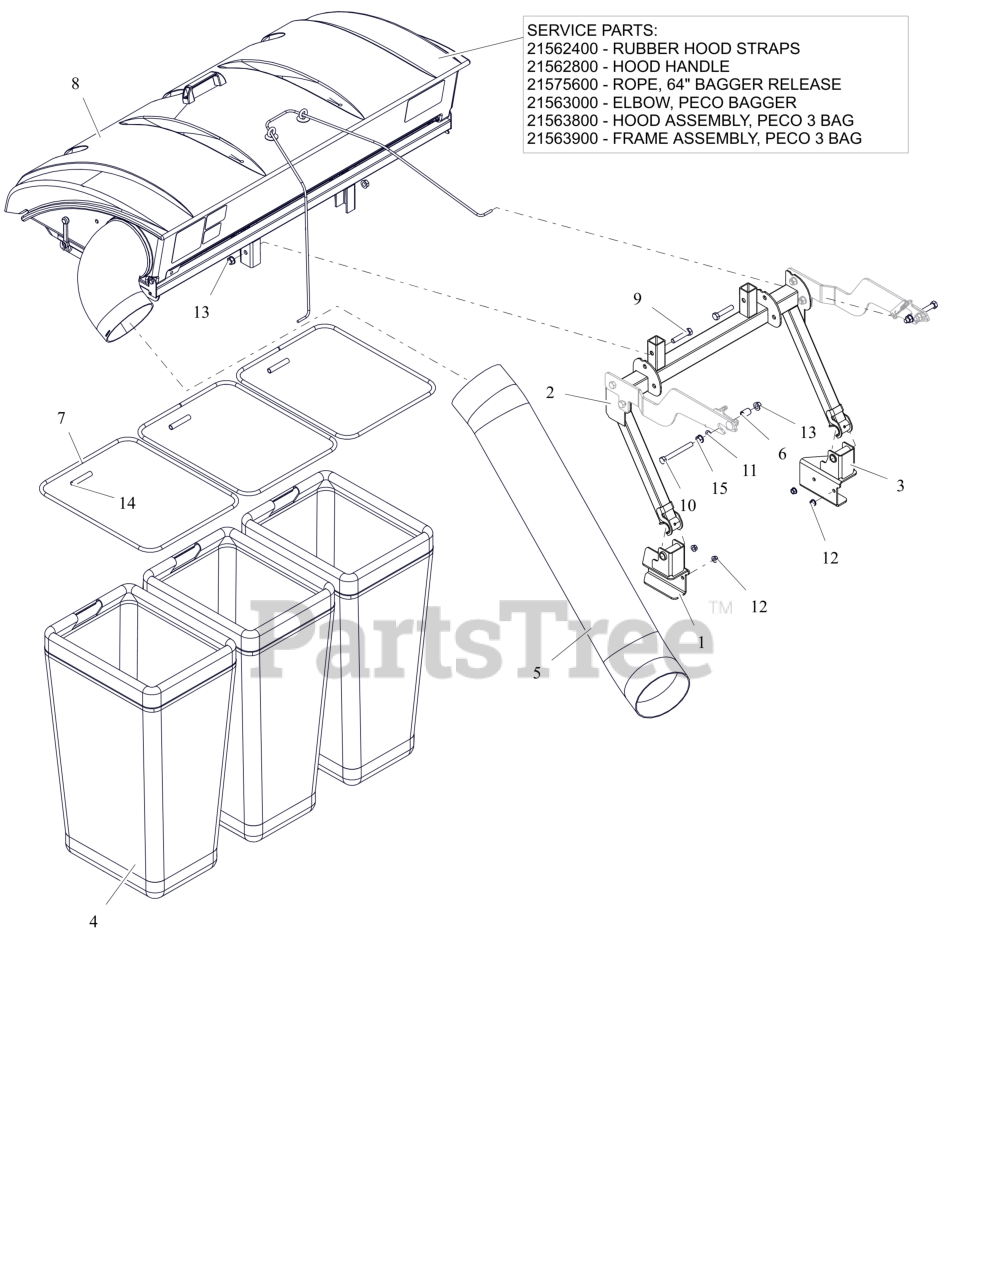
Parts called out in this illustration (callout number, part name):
1	WLDMT, BAGGER MNT RH - BLACK
2	WLDMT, BAGGER POST - BLACK
3	WLDMT, BAGGER MNT LH - BLACK
4	BAG, DEBRIS COLLECTION
5	HOSE BAGGER, 49"
6	BSHG, .515ID X .75ODX 1.080
7	FRAME, BAG
8	BAGGER, PECO 3 BAG RECEPTACLE
8	CLAMP, 7' BAGGER HOSE
8	RUBBER HOOD STRAP
8	HANDLE
8	ROPE, 58" BAGGER RELEASE
8	ELBOW, PECO BAGGER
8	HOOD ASSEMBLY, PECO 3 BAG
8	FRAME ASSEMBLY, PECO 3 BAG
9	BLT, HEX .50-13X2.50 G5 ZCC
10	BLT, HEX .50-13X4.50F G8 ZCC
11	WSHR, FLT .505X.880X.072 ZCC
12	NUT-LK-CTR-FLG .375-16 GF ZCC
13	NUT-LK-CTR-FLG .500-13 GG ZCC
14	HOSE, VINYL
15	NUT, SPNLK-FLG .50-13 G5 ZCC
